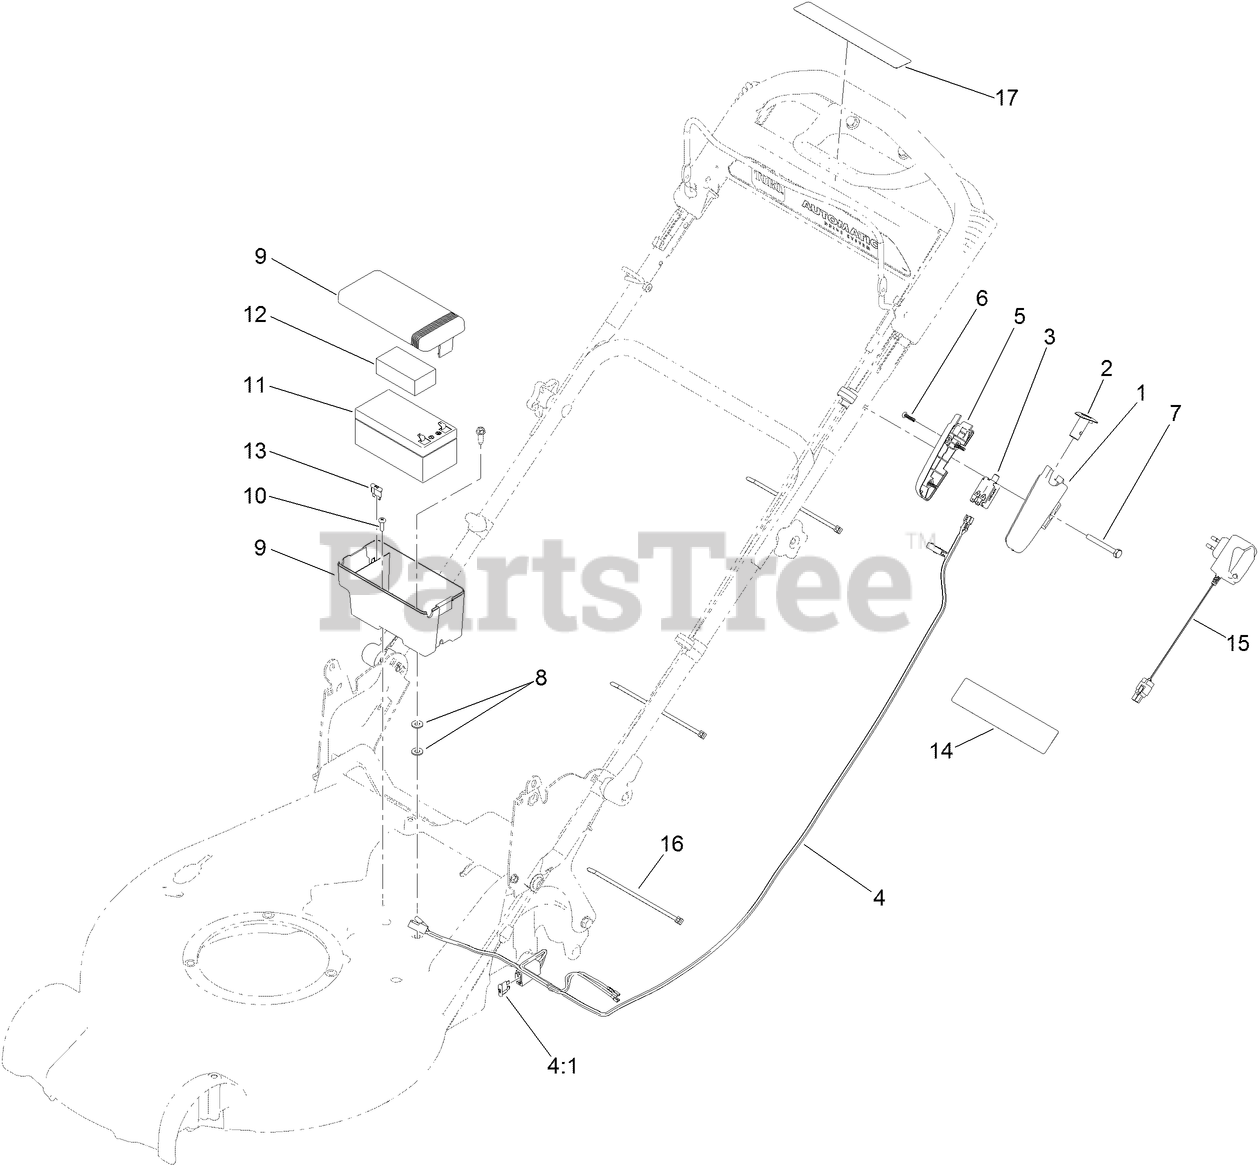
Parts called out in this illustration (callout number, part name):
1	HOUSING-SWITCH, LH
2	BUTTON-SWITCH
3	SWITCH-PUSH BUTTON
4	HARNESS-WIRE
4:1	FUSE-40 AMP
5	HOUSING-SWITCH, RH
6	SCREW-PPH
7	SCREW-HH
8	WASHER-FLAT
9	BATTERY BOX ASM
11	BATTERY-WET
12	FOAM-BATTERY, TOP
13	FUSE-40 AMP
14	DECAL-WARNING
16	TIE-CABLE
17	DECAL-BUTTON, PUSH
